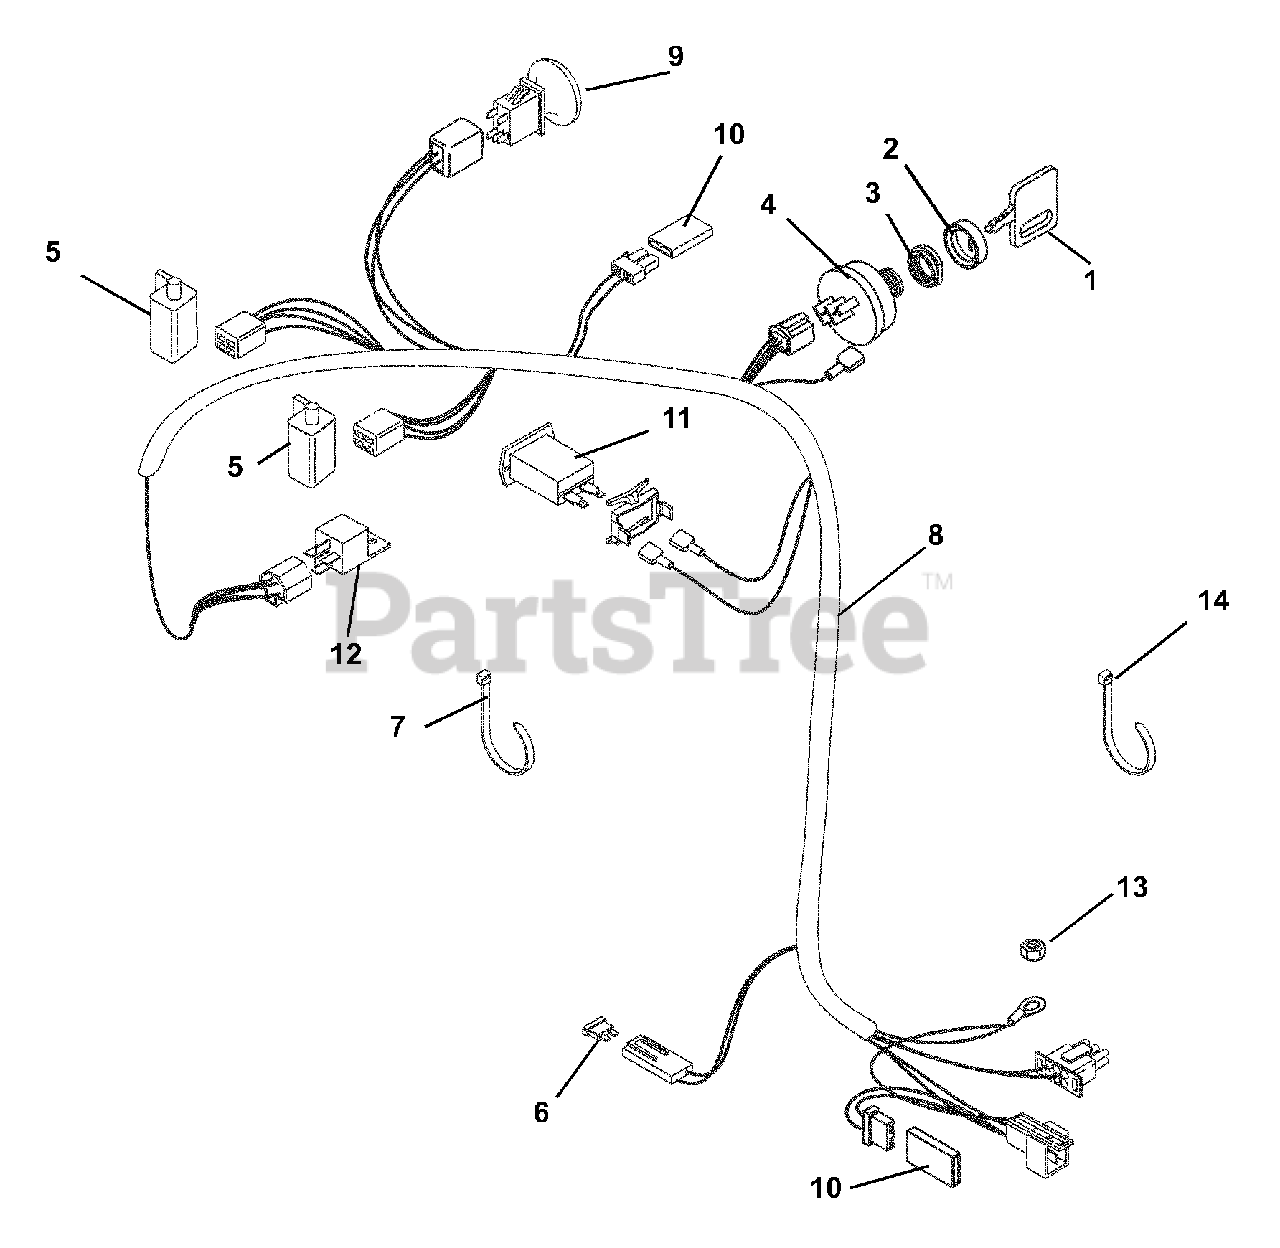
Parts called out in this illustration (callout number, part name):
1	KEY -W/CAP
2	CAP - IGNITION SWITCH
3	NUT- PANEL .562-24 GRECO
4	KEY SWITCH
5	SWITCH- SINGLE POLE N.O.
6	FUSE-25 AMP ATC TYPE
7	CABLE TIE LG 5-1/2
8	HARNESS-WIRE-GEAR RECOIL-ERGO
9	SWITCH - PTO - NMIR
10	DIODE, CONNECTOR SHELL
11	HOURMETER-QUARTZ 80VDCMAX
12	RELAY
13	@NUT-LK-TOP-FLG .31-18 YWZC
14	TIE WRAP
